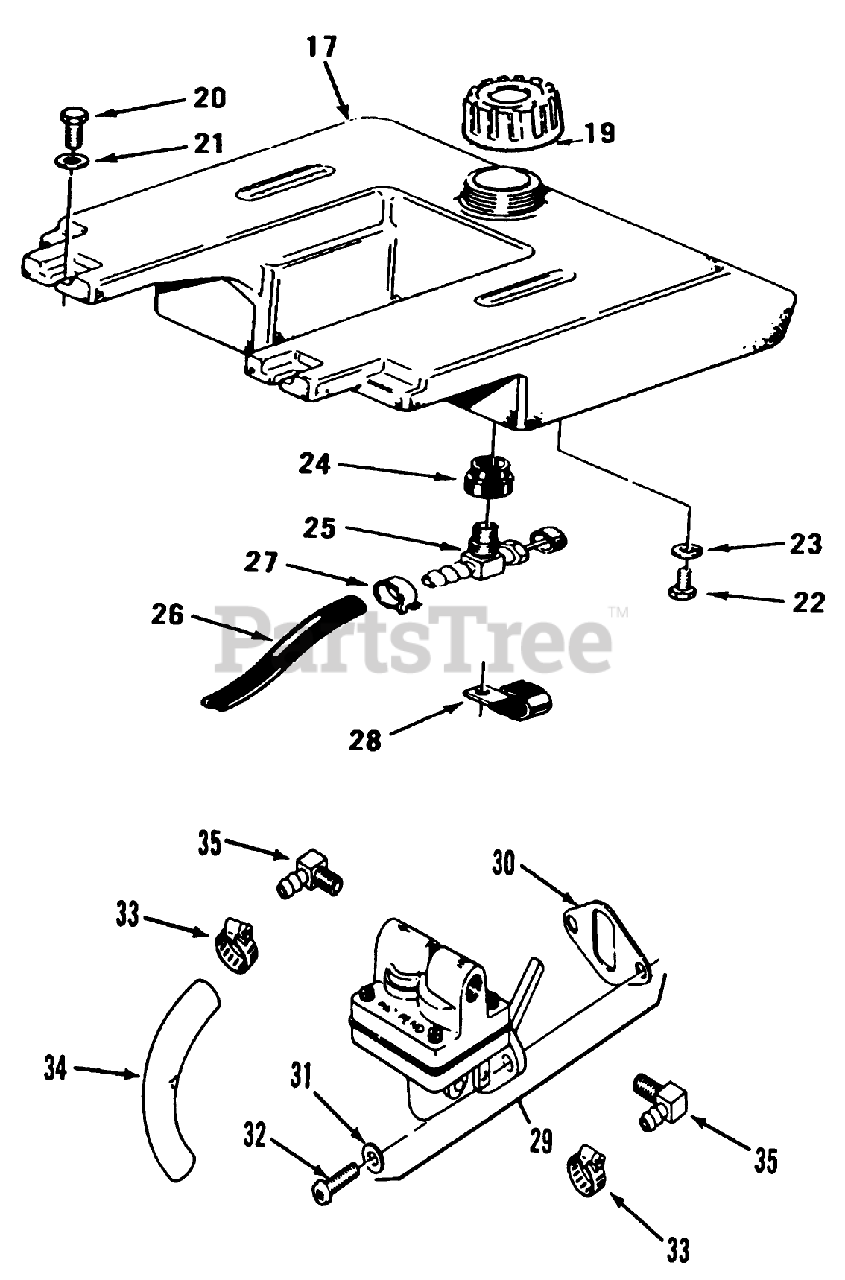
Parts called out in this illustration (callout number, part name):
17	TANK-FUEL
18	GAS CAP ASM
21	WASHER-FLAT
22	SCREW-HH
23	WASHER-LOCK
25	VALVE-FUEL
29	KOHLER 47-559-08
30	Gasket
31	KOHLER X-25-63
32	KOHLER X-174-2
33	KOHLER X-426-9
34	KOHLER 25-353-01
35	KOHLER 25-155-02
